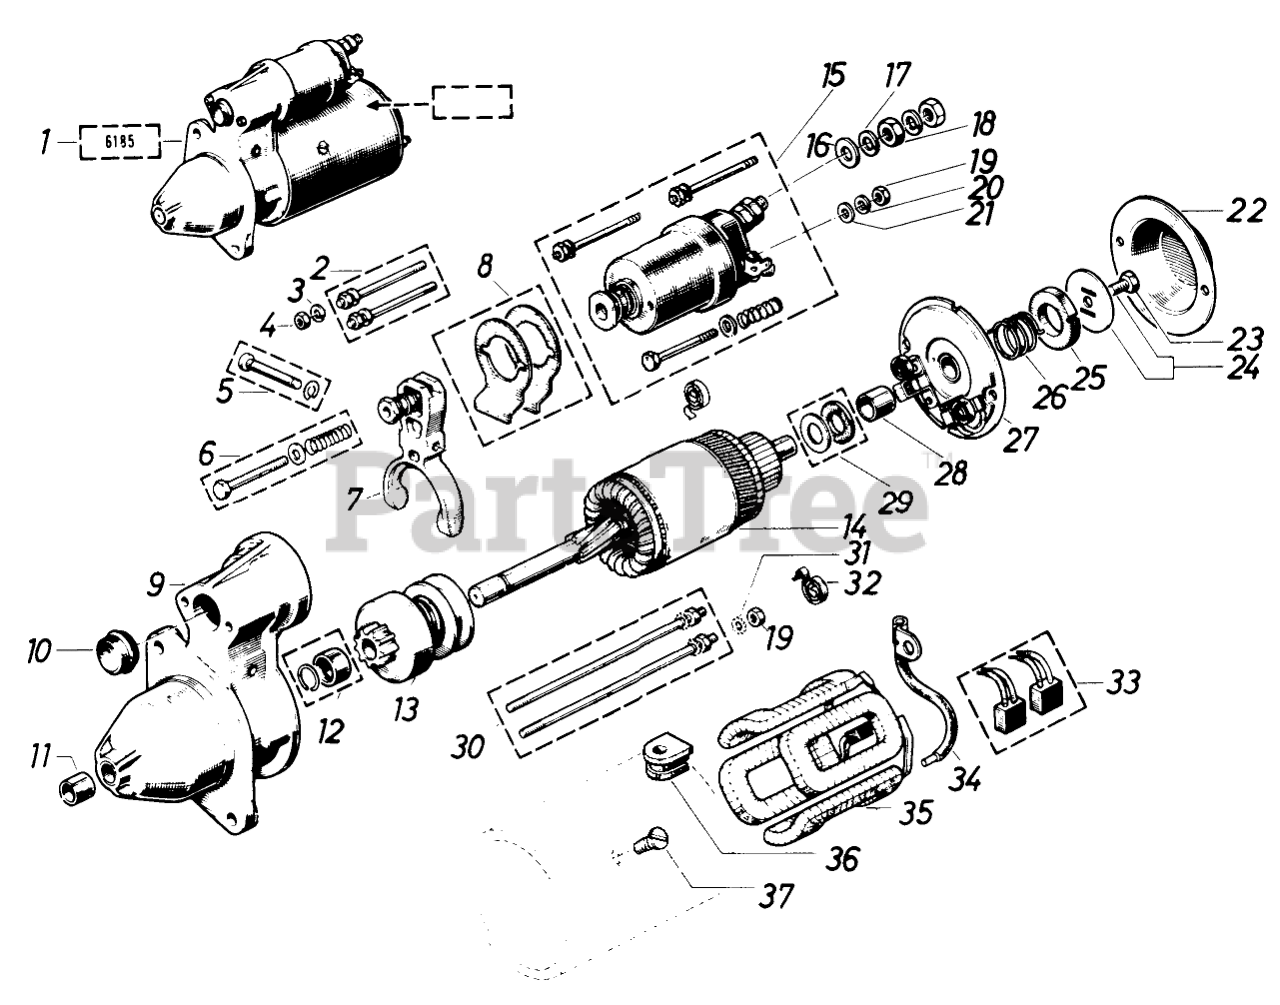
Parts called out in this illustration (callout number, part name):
1	Starter
2	Screw Set
3	Lock Washer
5	Bolt with Lock
6	Screw Assy
7	Shift Fork
8	Protection Plate
9	Driving End Bearing
10	Rubber Plug
11	Bushing
12	Stop for Drive Wheel
13	Drive Wheel
14	Armature
15	Solenoid Assy
16	Washer
17	Spring Washer
20	Spring Washer
21	Washer
22	End Plate
23	Screw
24	Brake Disc
26	Spring
27	Commutator End Plate Assy.
28	Bushing
29	Washer Set
30	Screw Set
31	Washer
32	Spring
33	Brush Set
34	Cable
35	Field Winding
36	Rubber Sleeve
37	Screw
